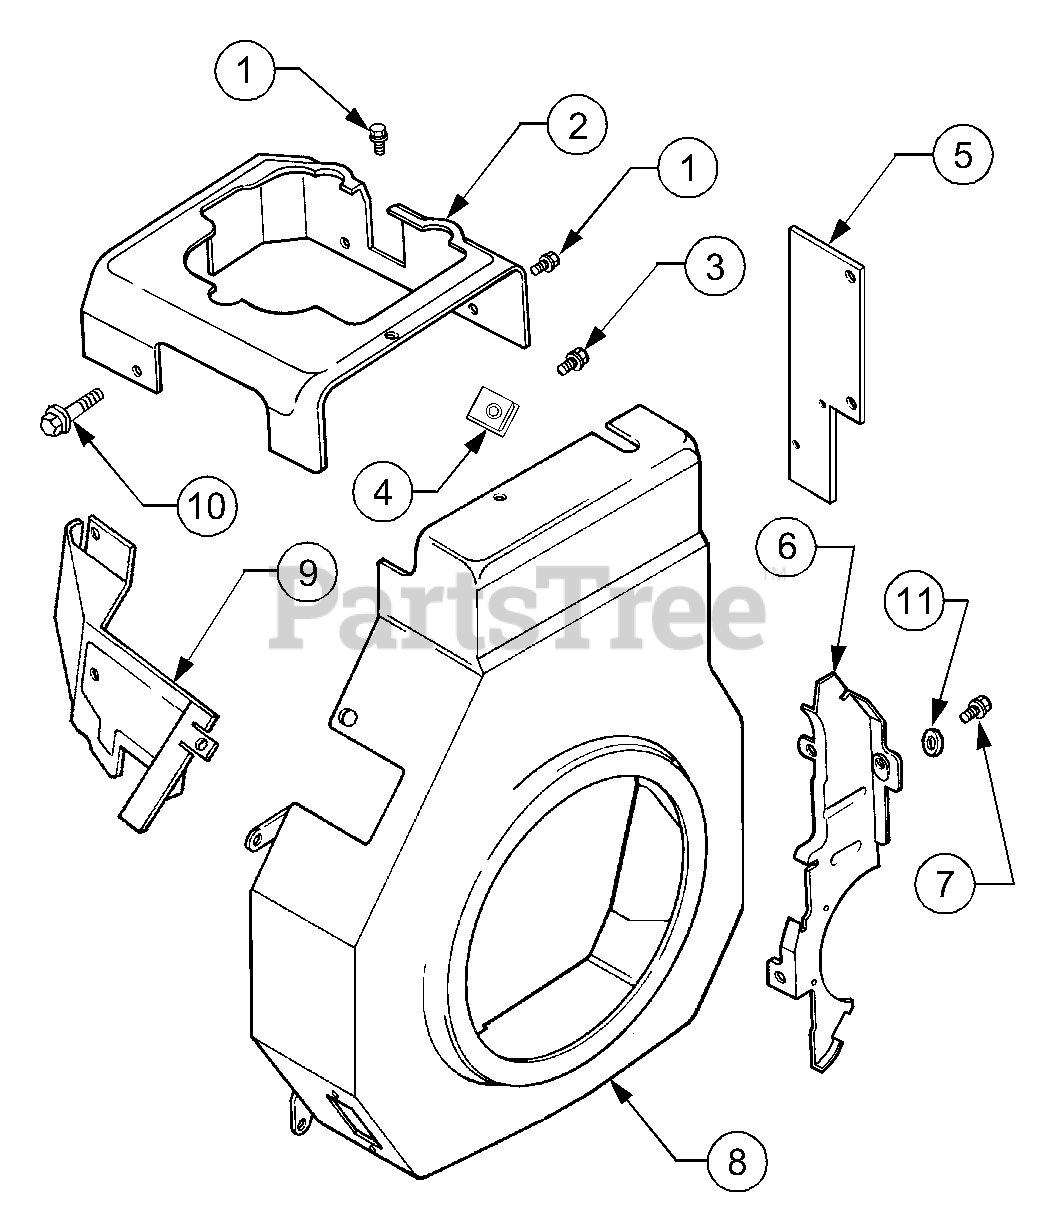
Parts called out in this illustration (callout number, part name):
1	Screw, Hex Flange, M5 x .8 x 10
2	Baffle, Cylinder Head
3	Screw, Hex Flange, M5 x .8 x 16
4	Clip, Mounting
5	Baffle, Cylinder
6	Plate, Blower Housing
7	Screw, w/Washer M5 x .8 x 20
8	Housing, Blower
9	Baffle, Intake Side
10	Screw, Hex Flange, M5 x 0.8 x 10
11	Washer, Plain 1/4"
